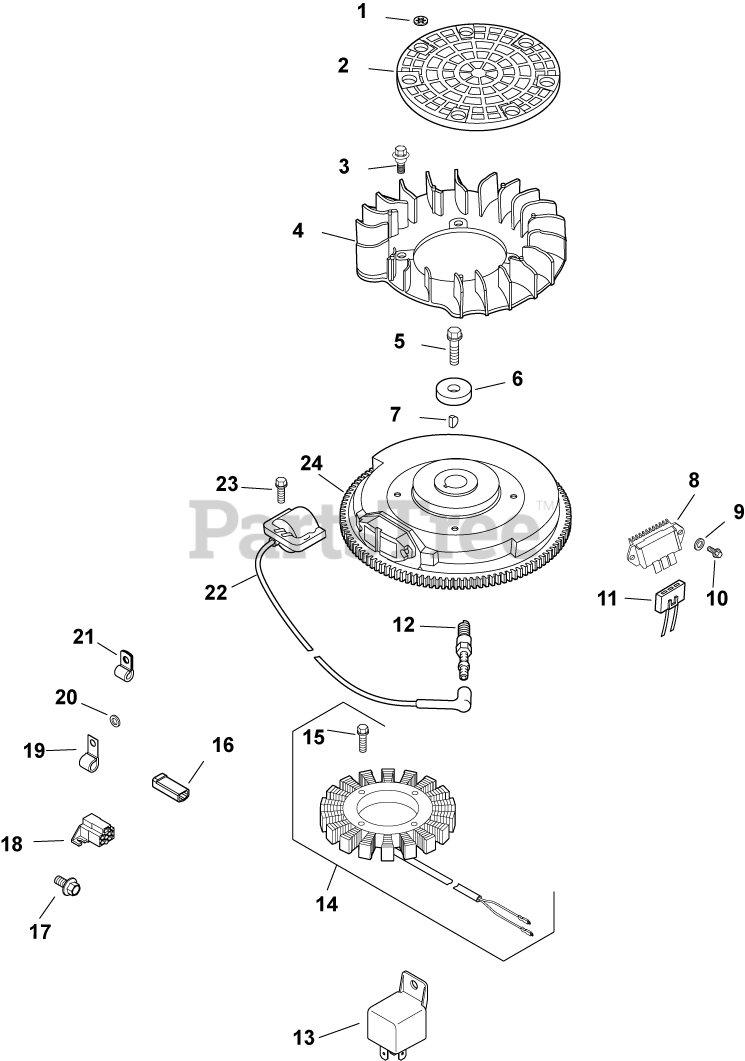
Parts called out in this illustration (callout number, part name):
2	SCREEN, GRASS
3	BOLT, SHOULDER
4	FAN (KM)-USE 24 157 15-S
5	SCREW, FLG M10X1.5X45 - (#25086361S)
6	WASHER, FLAT 13/32"
7	KEY, 3/16" X 5/8"
8	REG/RECTIFIER (20/25 AMP)-USE 25 403 20-
9	WASHER, FLAT 3/16"
10	SCREW, PHL HD #11-16X7/8"
11	CONNECTOR, BODY (KM)-USE 25 155 41-S
12	PLUG, SPARK (PRO SERIES)
14	STATOR KIT - USE 237878-S
15	SCREW, M5X0.8X25 - (#25086402S)
16	CONNECTOR (1 CONTACT)
17	SCREW, FLG M6X1.0X12
18	CONNECTOR
19	CLIP, TUBE & WIRING (KM)
20	WASHER, FLAT 1/4" (O.D. 1/2")
21	CLIP, CABLE
22	MODULE, IGNITION-USE 24 584 45-S
23	SCREW, FLG THD FRM M5X.8X20-(#25086399S)
24	FLYWHEEL, PAINTED-USE 24 025 55-S
